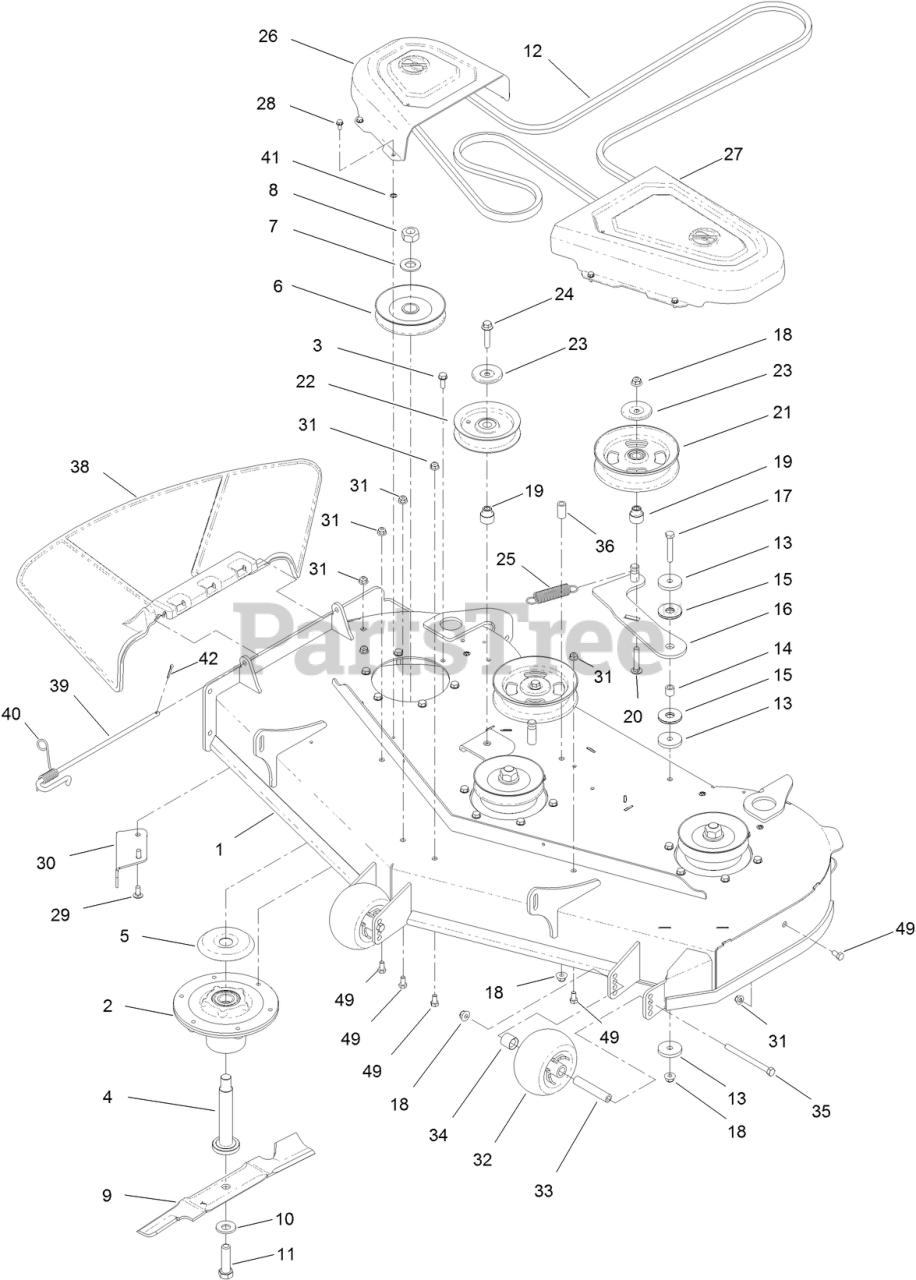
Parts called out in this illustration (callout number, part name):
1	DECK ASM-48"
2	SPINDLE ASM
3	SCREW-TAPTITE
4	SHAFT-SPINDLE
5	SHIELD-BEARING
6	PULLEY
7	WASHER
8	NUT-HEX
9	BLADE - HI FLOW, 16.50 IN
10	WASHER-BELLEVILLE
11	SCREW-BLADE
12	BELT, DECK
13	WASHER-PLAIN
14	BUSHING-IDLER
15	WASHER-FRICTION, COMPOSITE
16	IDLER ARM ASM
17	SCREW-HH
18	NUT-HF, NI
19	BUSHING-IDLER
20	SCREW-CARR
21	PULLEY-IDLER, FLAT
22	PULLEY-IDLER, FLAT
23	SHIELD-DUST
24	SCREW-HHF
25	SPRING-EXTENSION
26	COVER-BELT, RH
27	COVER-BELT, LH
28	SCREW-HWH
29	SCREW-CARR
30	BAFFLE-CUTOFF
31	NUT-HF, NI
32	ROLLER-SCALP, ANTI
33	TUBE-SPANNER
34	SPACER-AXLE, REAR
35	SCREW-HH
36	SPACER-FENDER
38	DEFLECTOR-DISCHARGE
39	PIN-CHUTE
40	SPRING-TORSION
41	NUT-RETAINING
42	PIN-COTTER
49	SCREW-HH
